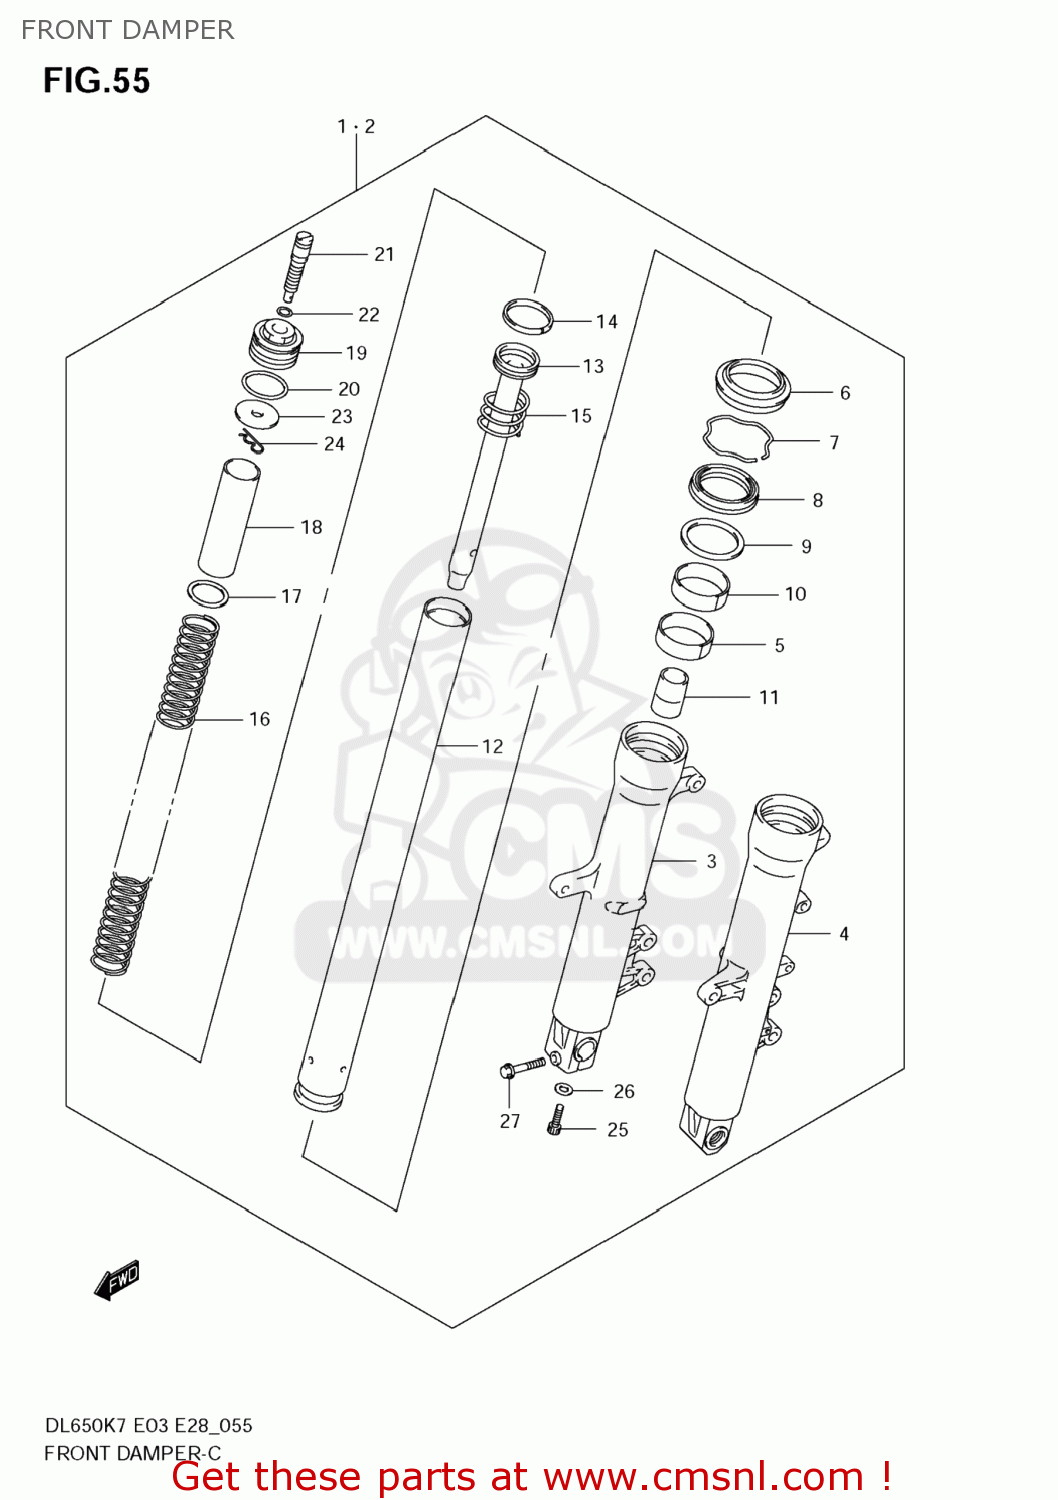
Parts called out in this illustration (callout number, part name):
1	DAMPER ASSY,FR FORK,R
2	DAMPER ASSY,FR FORK,L
3	TUBE,OUTER,R
4	TUBE,OUTER,L
5	BUSH,SLIDE
6	SEAL,DUST
7	CIRCLIP,FORK OIL SEAL
8	SEAL,OIL
9	SPACER,SEAL
10	BUSH,GUIDE
11	PIECE,OIL LOCK
12	TUBE,INNER
13	CYLINDER
14	RING,PISTON
15	SPRING,REBOUND
16	SPRING,FR
17	SEAT,SPRING LWR
18	COLLAR,SPRING
19	BOLT,FORK
20	O RING
21	ADJUSTER BOLT,SPRING
22	O RING
23	SEAT,SPRING
24	PIN,SEAT SPRING
25	BOLT(8X27)
26	GASKET (NAS)
27	BOLT(8X40)
